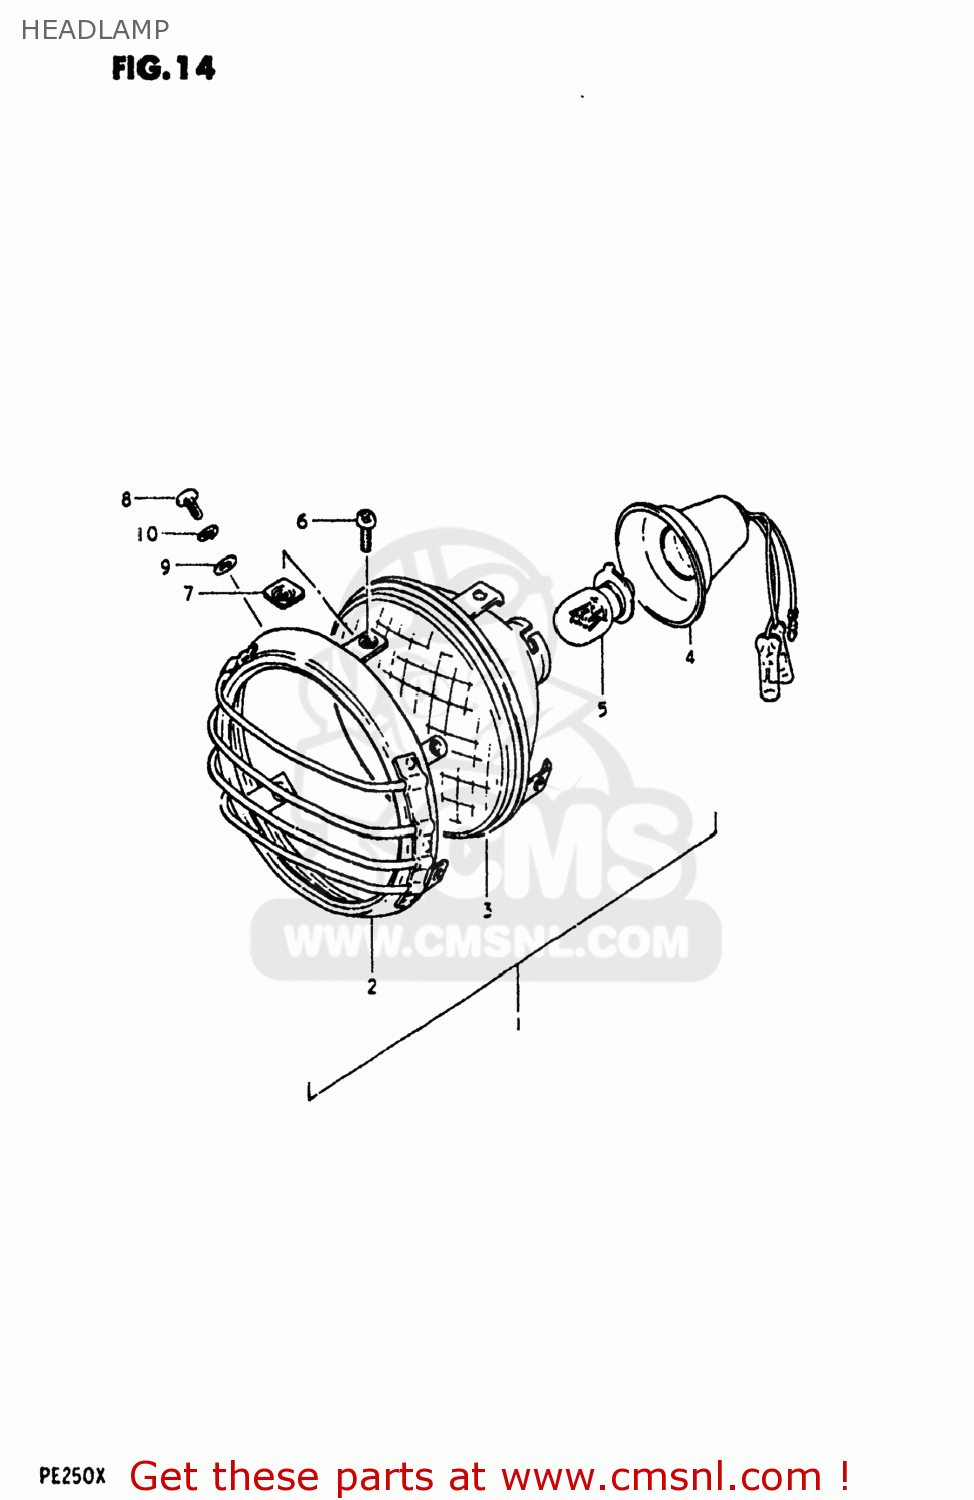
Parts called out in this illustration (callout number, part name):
1	HEADLAMP ASSEMBLY
2	RIM,HEADLAMP
3	LAMP UNIT
4	SOCKET,HEADLAMP
5	BULB(6V15/15W/STANLEY,A3598HA)
6	SCREW
7	NUT
8	SCREW
9	WASHER
10	LOCK WASHER
